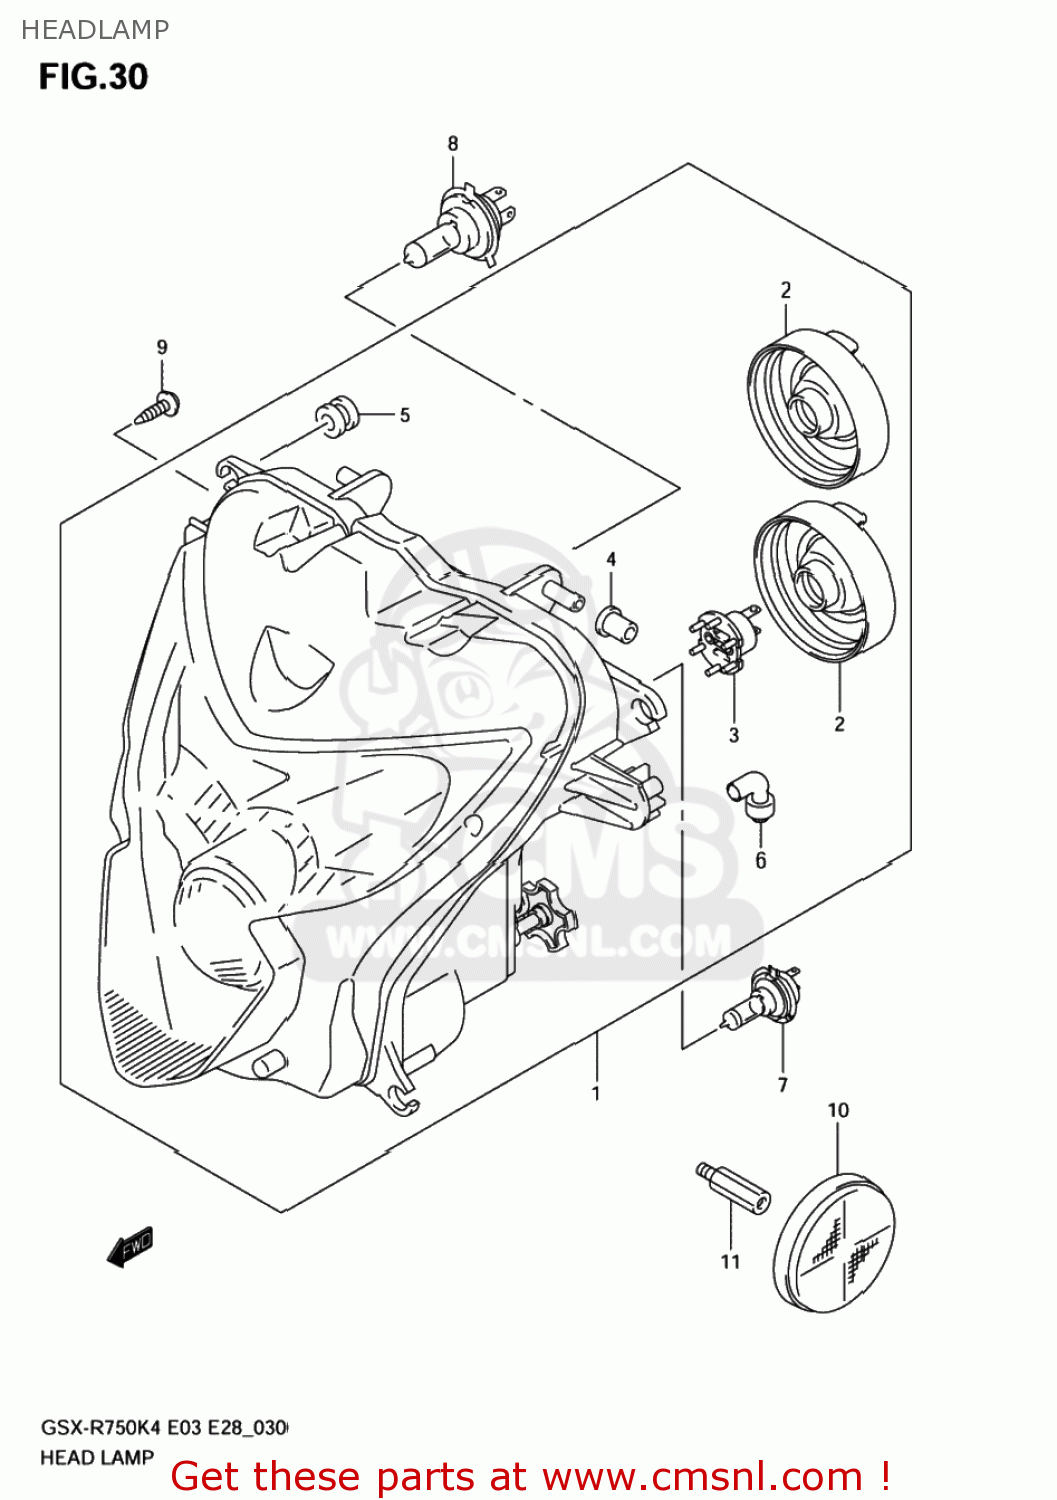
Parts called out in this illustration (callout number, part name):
1	HEADLAMP ASSY
2	COVER,SOCKET
3	ADAPTER ASSY
4	CUSHION
5	CUSHION
6	TUBE ASSY
7	BULB(12V55W/H7/PX26D/PHILIPS)
8	BULB(12V60/55W,H4)
9	SCREW(5X15)
10	REFLECTOR,REFLEX FR
11	BOLT
